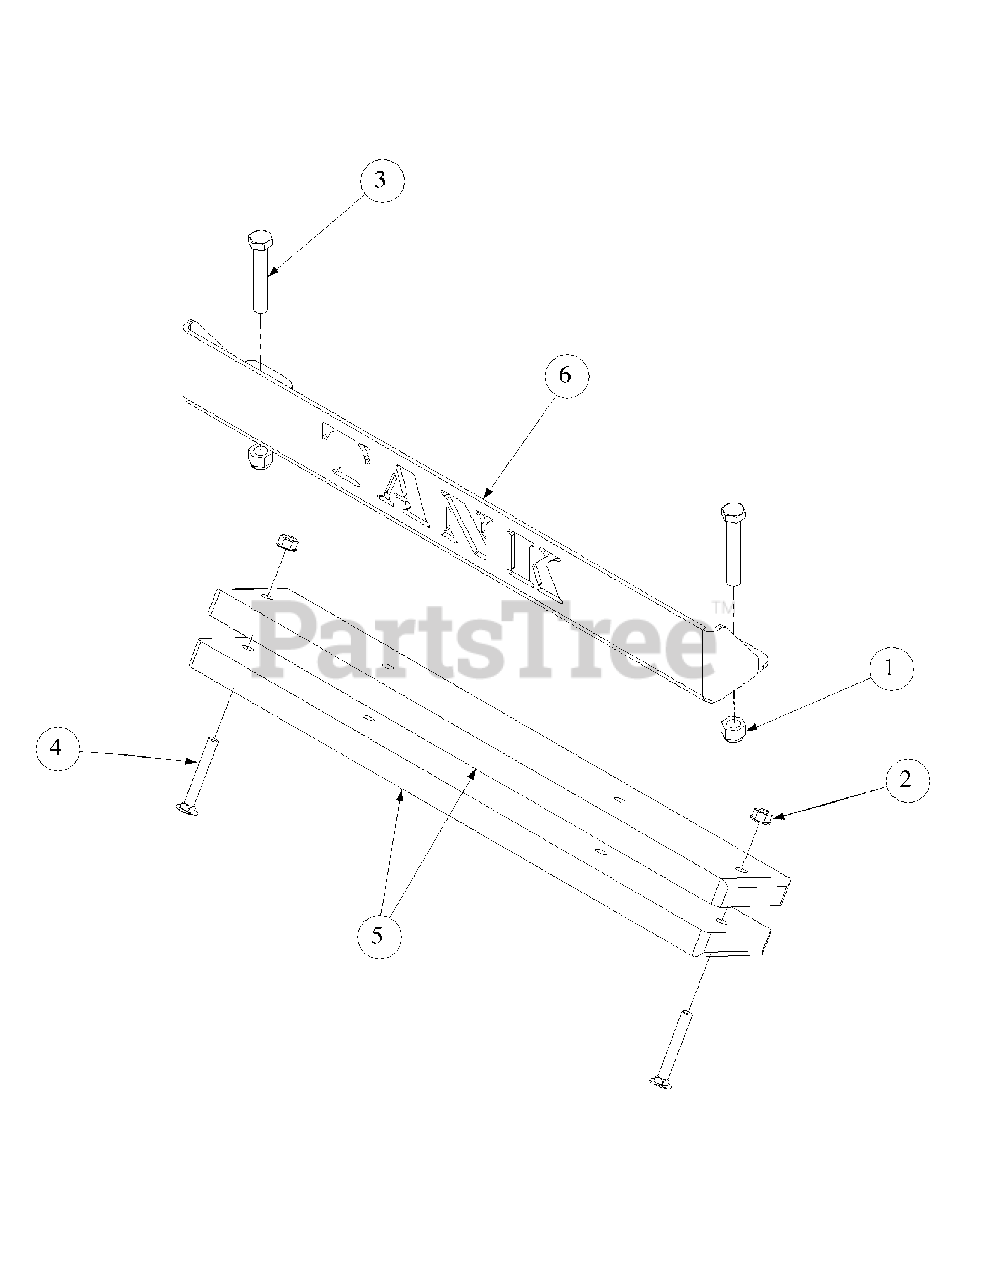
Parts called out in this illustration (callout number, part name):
1	Hex Nut, 1/2-13, Insert Lock
2	Nut, Hex 3/8-16 Flange Lock
3	HHCS, 1/2-13, 3.00
4	Carriage Bolt, 3/8-16 x 2.75
5	Bar, Weight
6	Rear Bumper Plate
